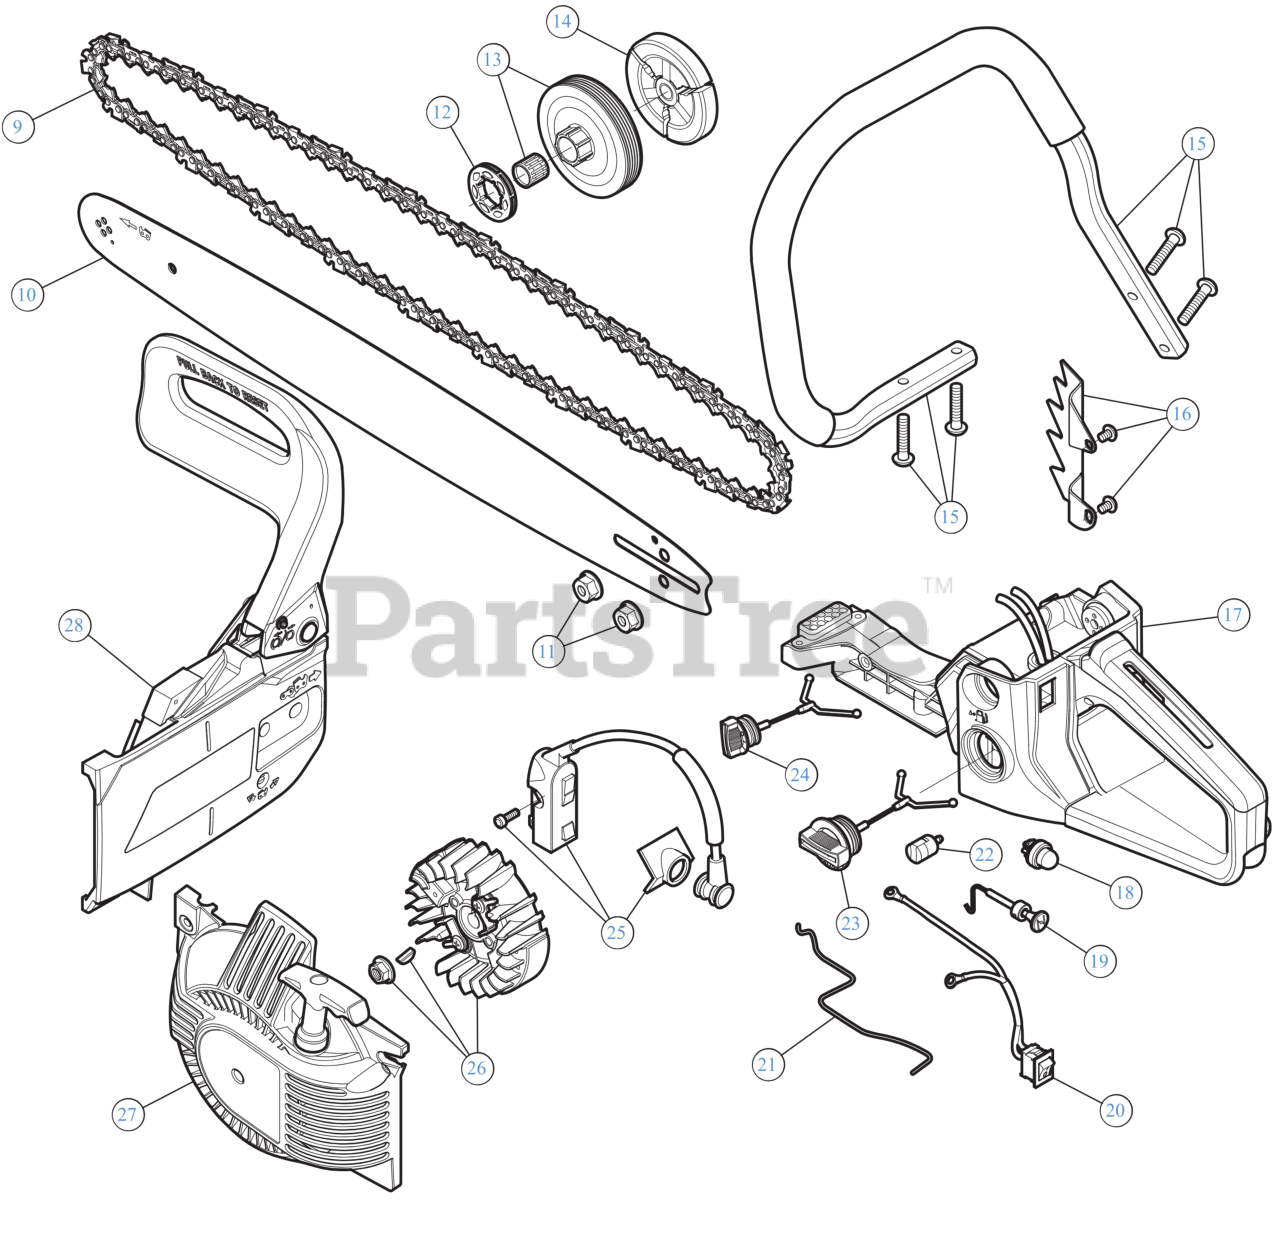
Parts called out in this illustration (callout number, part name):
9	20" CHAINSAW CHAIN
10	20" BAR
11	BAR NUT M8
12	SPROCKET
13	CLUTCH DRUM ASSEMBLY
14	CLUTCH ASSEMBLY
15	HANDLE ASSEMBLY
16	SPIKE PLATE W/HDW
17	FUEL HOUSING ASSEMBLY
18	PRIMER BULB YD2500-18410
19	CHOKE LEVER ASSEMBLY
20	SWITCH ASSEMBLY
21	THROTTLE ROD
22	FUEL FILTER YD4600-18034
23	FUEL CAP ASSEMBLY SRS
24	OIL CAP ASSEMBLY
25	MODULE
26	FLYWHEEL
27	RECOIL ASSEMBLY (SBD4620YD4620.8CM-25313)
28	BRAKE ASSEMBLY (SBD4620 YD4620.8CM-27724)
